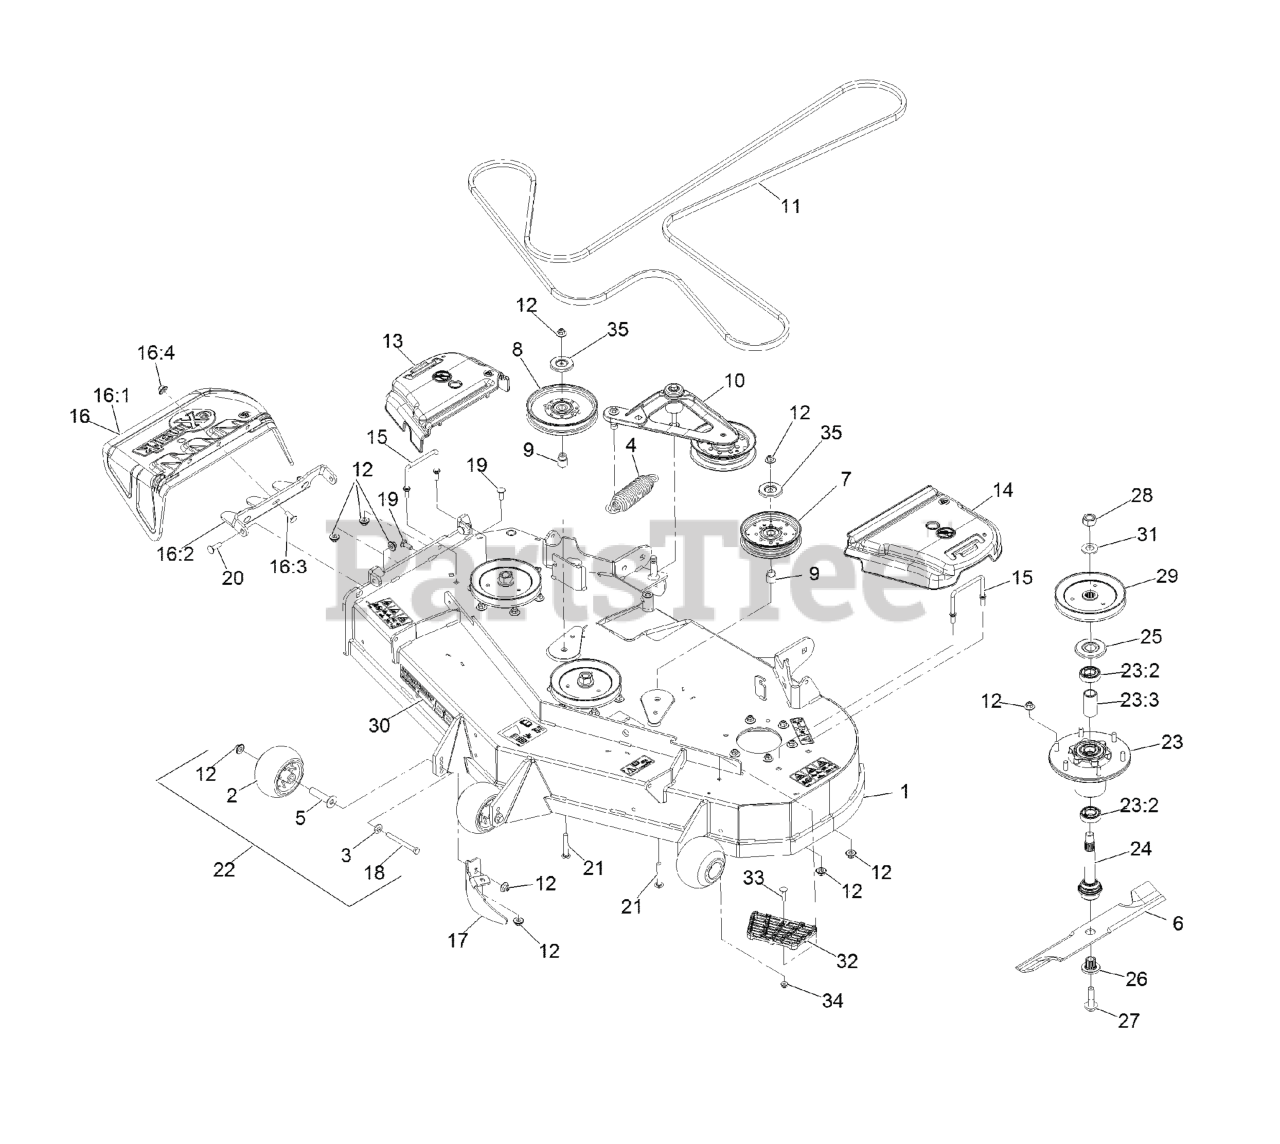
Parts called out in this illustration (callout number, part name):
1	ASM,DECK W/ DECALS 52
2	ROLLER-SCALP, ANTI
3	WASHER-BELLEVILLE
4	SPRING-EXTENSION
5	AXLE, ROLLER
7	PULLEY-IDLER, FLAT
8	IDLER-PULLEY
9	BUSHING-IDLER
10	DECK IDLER ASM
12	Nut-Nyloc 3/8-16 Flg
13	COVER-BELT, RH
14	COVER-BELT, LH
15	WIREFORM-COVER
16	ASM,DISCHARGE CHUTE
16:1	CHUTE,DISCHARGE
16:2	BRACKET,DISCHARGE CHUTE
16:3	SCREW-CARR
16:4	Nut-Nyloc 3/8-16 Flg
17	BAFFLE-DOGLEG, LZ-VT52
18	SCREW-HH 3/8-16 X 3 3/4 GR 8
19	SCREW-CARR
20	Bolt-Carriage 3/8-16 X 1 1/4
21	SCREW-CARR
22	KIT, ANTI-SCALP ROLLER
23	ASM-CUTTER HSG WITH BEARINGS
23:2	BEARING-BALL
23:3	SPACER-BEARING
24	ASM-SPINDLE AND SEAL
25	GUARD,BEARING TOP .989
26	BUSHING,SPLINED
27	SCREW,SEMS 1/2-20 X 2.19
28	NUT-HEX
29	SHEAVE,BLADE DRIVE 6.50
30	DECAL, 524
32	STEP-DECK
33	Bolt-Carriage 5/16-18 X 1 1/4
34	NUT-HF, NI
35	SHIELD-DUST
